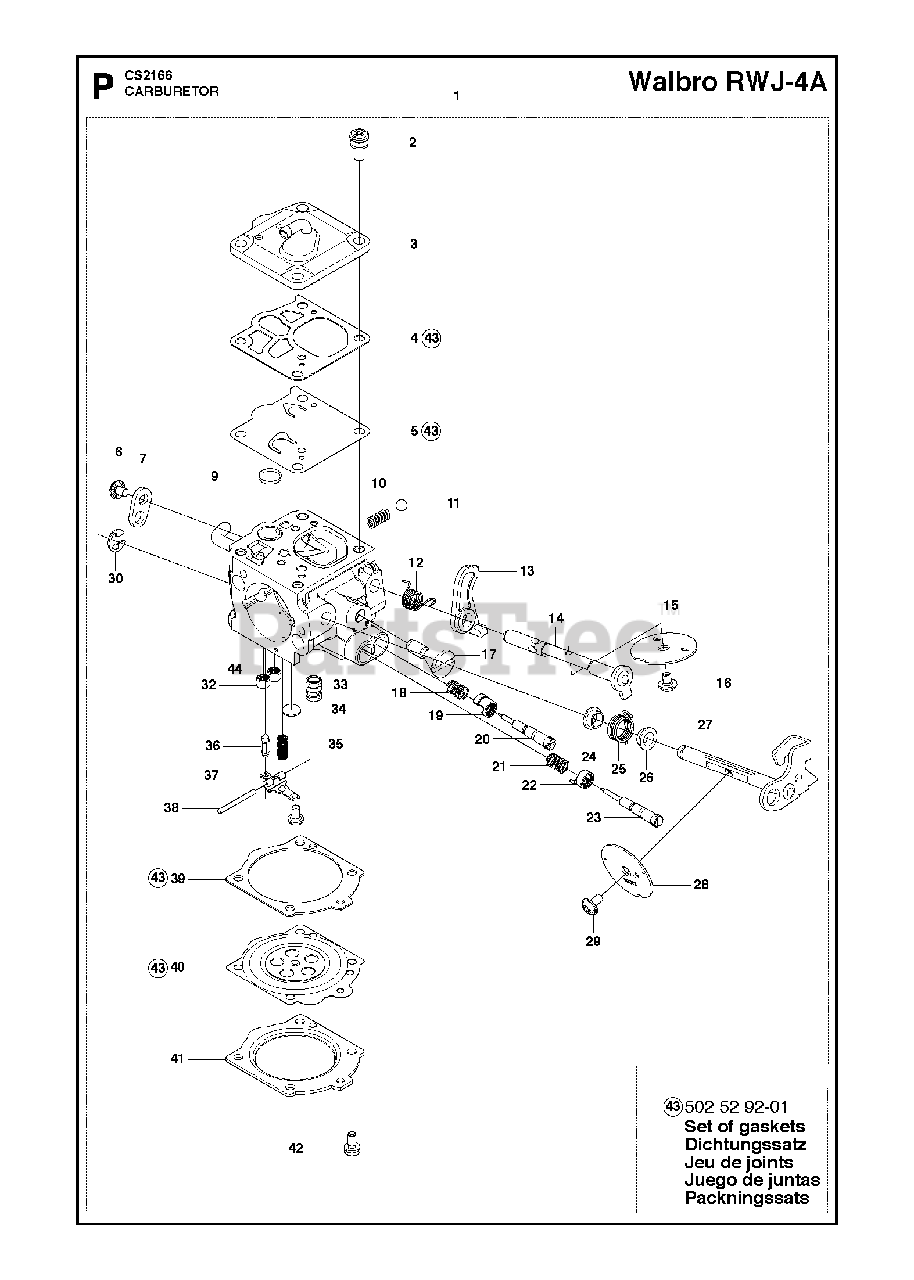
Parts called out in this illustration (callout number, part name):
1	CARBURETOR
2	SCREW W/ WASHER
3	PUMP COVER
4	GASKET
5	DIAPHRAM PUMP
6	SCREW.
7	LEVER CHOKE
9	FUEL INLET SCREEN
10	SPRING 394
11	BALL 394
12	SPRING CHOKE
13	LEVER
14	SHAFT ASSY
16	SCREW
17	SCREW
18	SPRING
19	LIMITER CAP
20	NEEDLE
21	SPRING
22	LIMITER CAP
23	NEEDLE
25	%SPRING
27	SHAFT ASSY
28	VALVE
29	SCREW
30	E CLIP
32	CHECK VALVE
33	NOZZLE ASSY
34	PLUG WELCH
35	SPRING
36	INLET NEEDLE
37	LEVER
38	PIN
39	GASKET
40	SPRING
41	DIAPHRAM COVER
42	SCREW W/ WASHER
43	GASKET KIT
